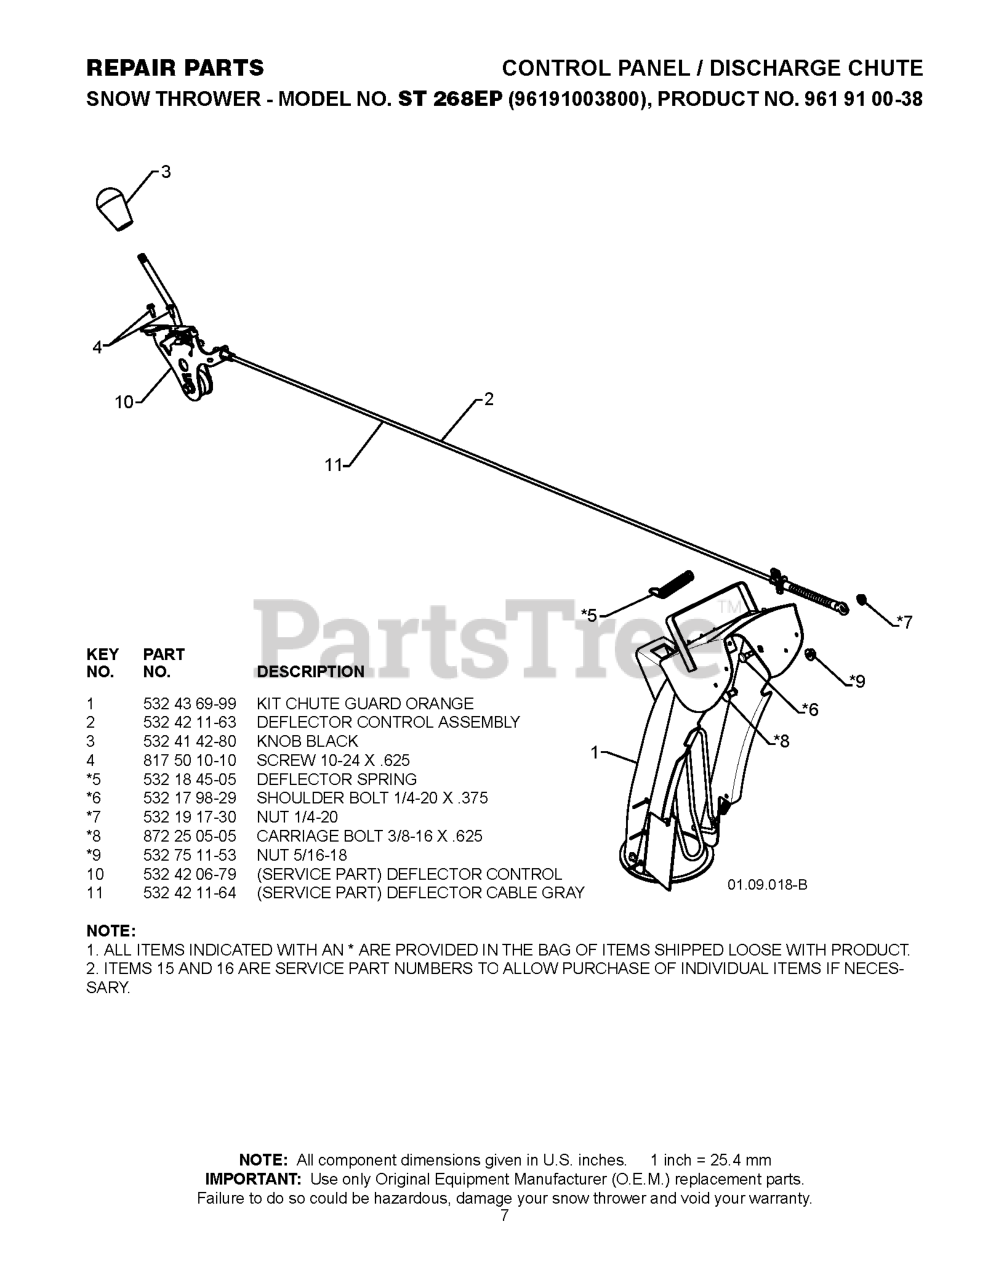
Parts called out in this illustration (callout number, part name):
2	CONTROL.ASM.DEFLECTOR
3	KNOB LEVER, BLACK
4	SCREW #10-24 X 5/8
10	RP CNTRL.HEAD.ASSEM.DEFLECTOR
11	SERVICE.CHUTE.DEF.CBL.GRY
